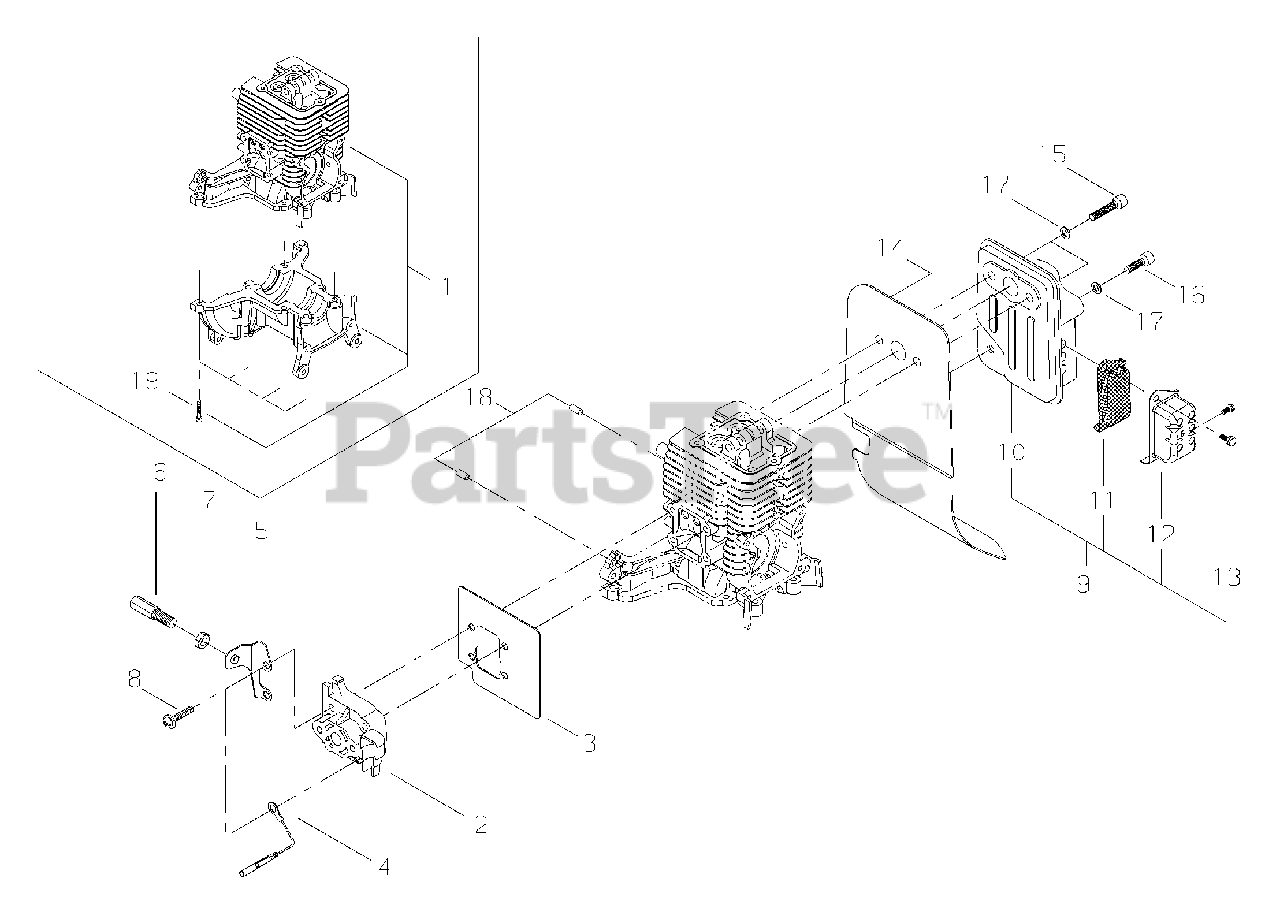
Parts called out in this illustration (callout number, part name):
1	CYLINDER & CRANKCASE ASSY
2	INSULATOR WITH REED VALVE
3	HEAT SHIELD, INTAKE
4	LEAD - GROUND L= 110 MM
5	BRACKET, THROTTLE CABLE
6	ADJUSTER, THROTTLE CABLE
7	NUT, ADJUSTER LOCK M6
8	SCREW M5×25
9	MUFFLER ASSY
10	MUFFLER
11	SCREEN, SPARK ARRESTER
12	GUIDE, EXHAUST
13	SCREW M4×6
14	HEAT SHIELD, EXHAUST
15	BOLT M5×25
16	BOLT 5×16
17	WASHER, FLAT 5.5×10×0.8
18	PIN, LOCATING Ø4×8
19	BOLT 5×16
